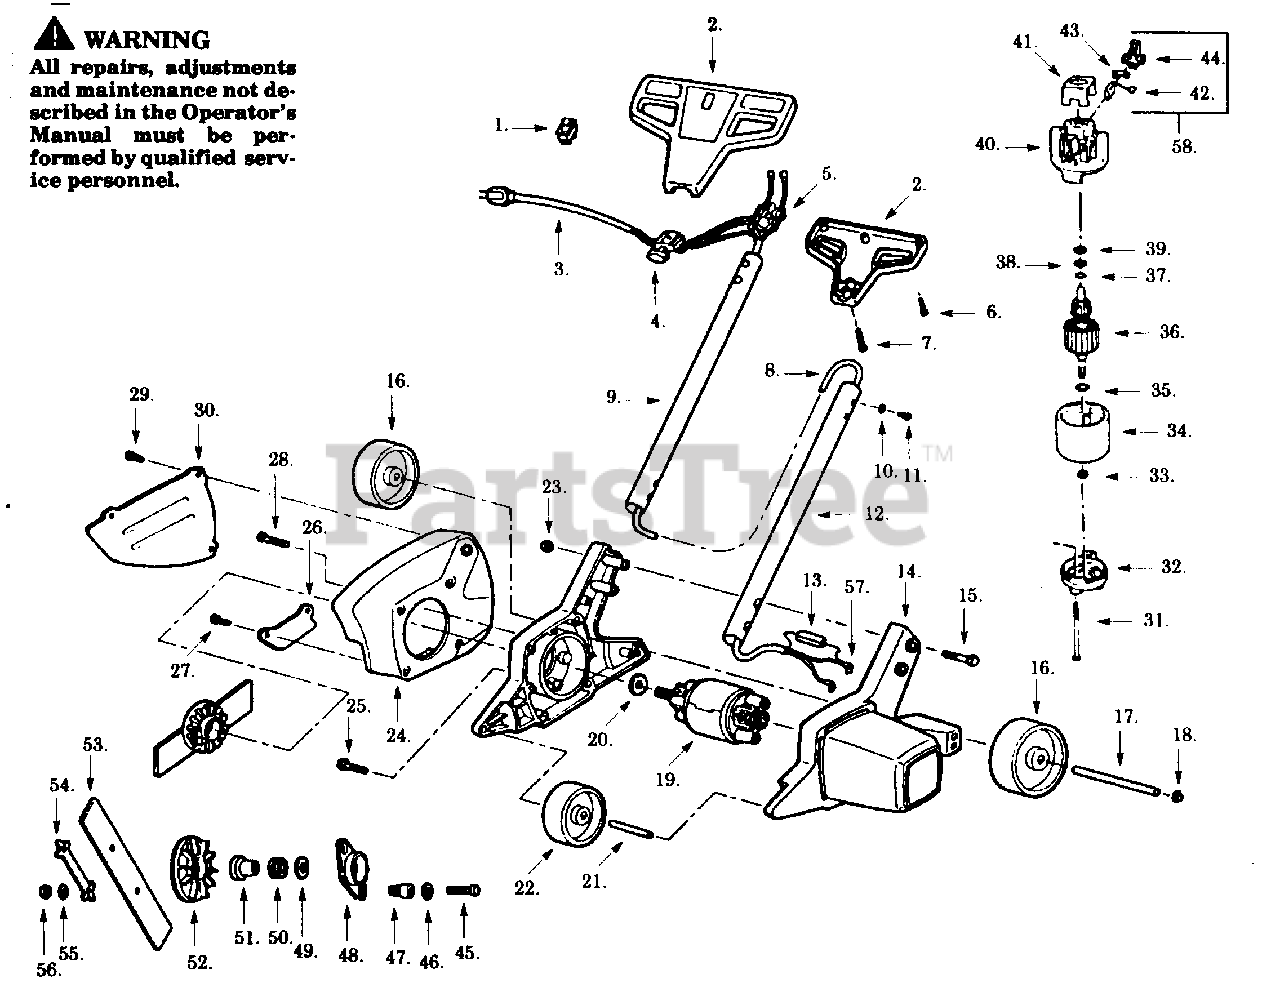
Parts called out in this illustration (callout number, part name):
1	Power Switch
2	Handle Set
3	Power Cord
4	Trigger Switch
5	P.C. Bridge Kit
9	Upper Handle Tube
10	Lockwasher
12	Lower Handle Tube
13	Resistor
14	Motor Cover
18	Push Nut
23	Lock Nut
24	Guard Housing
26	Edge Guide
30	Side Guard
32	Endbell Ass'y. (Drive)
34	Field Ass'y.
35	Retaining Ring
36	Armature Ass'y.
37	Retaining Ring
40	Endbell Ass'y. (Brush)
41	Insulator
43	Brush Spring
44	Brush Holder
48	Clutch Plate
50	Spring Washer
51	Clutch Sleeve
54	Lockstrap
55	Lockwasher
57	Connector Tab
58	Brush Kit (Incl. 42,43,44)
